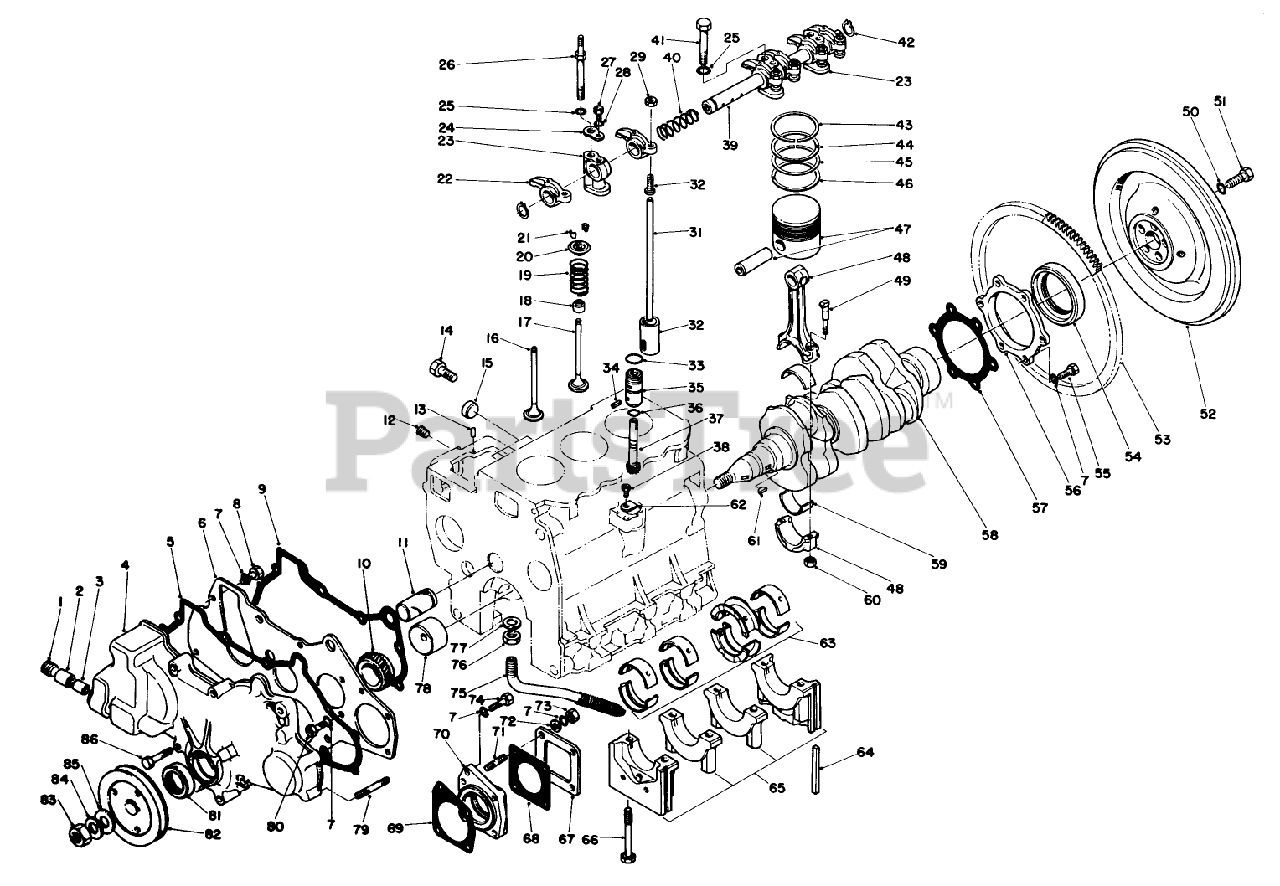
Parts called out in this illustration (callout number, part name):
1	TAPER PLUG MS 661123
2	NEEDLE BRG
3	NEEDLE BRG
4	GEAR CASE MM 408230
5	CASE GASKET
6	Plate, Front
7	WASHER-LOCK, SPRING
8	Screw-HH
9	PLT GASKET
11	IDLER SHAFT
12	Plug
13	Pin-Dowe
15	SEALING CAP
16	INTAKE VALVE
17	EXH VALVE MM 408455
18	Seal
19	VALVE SPRG MM 402381
20	SPRING RET MD 016482
21	RET LOCK MD 016483
22	ROCKER ARM
23	ROCKER STAY MM 314770
24	Washer Seat
25	WASHER-LOCK, SPRING
27	BOLT/WASHER
28	WASHER-LOCK, SPRING
29	JAM NUT
30	ADJ SCREW K 7231220
31	ROD - PUSH
32	TAPPET
33	O-RING MF 520012
34	SPRING PIN
35	GEAR SLEEVE
36	O-RING MD 701788
37	Gear, Speedmeter Driven
38	BOLT/WASHER
39	ROCKER SHFT MM 408935
40	SPRING LH MD 000962
41	SCREW-HH
42	RING-SNAP
43	PISTON RING SET
44	Ring Set, Piston 0.25 O.S.
45	Ring Set, Piston 0.50 O.S.
46	Ring Set, Piston 0.75 O.S.
47	Piston & Piston Pin Std.
48	CONNECTING ROD
49	Bolt Connecting Rod
50	SPEC SPRING WASHER
51	FLYWHEEL BOLT
52	Flywheel (Incl. Ref. #53)
53	GEAR RING
54	OIL SEAL
55	BOLT-WASHER ASM
56	SEAL CASE
57	SEAL GASKET
58	CRANKSHAFT MM 408811
59	BRG SET
60	CONN ROD NUT
61	5MMX19MM KEY
62	Plate-Locking
63	Bearing Set Crankshaft Std.
64	SEAL-SIDE
65	Cap, Assembly, Bearing
66	BOLT-BRG CAP
67	PUMP COVER K 7910451
68	COVER GASKET MM401206
69	HSG GASKET MM 409235
70	Housing, Pump Gear Bearing
72	Washer-Flat
73	NUT-HEX
74	Screw-HH
75	Screen Assembly Oil
76	NUT-HEX, JAM
77	WASHER MK 66114000
78	CAMSHFT BSHG
79	Stud (8 x 45)
80	BOLT
81	OIL SEAL
82	PULLEY
83	HEXNUT HNX 480180
84	Washer-Spring
85	WASHER
86	Capscrew
